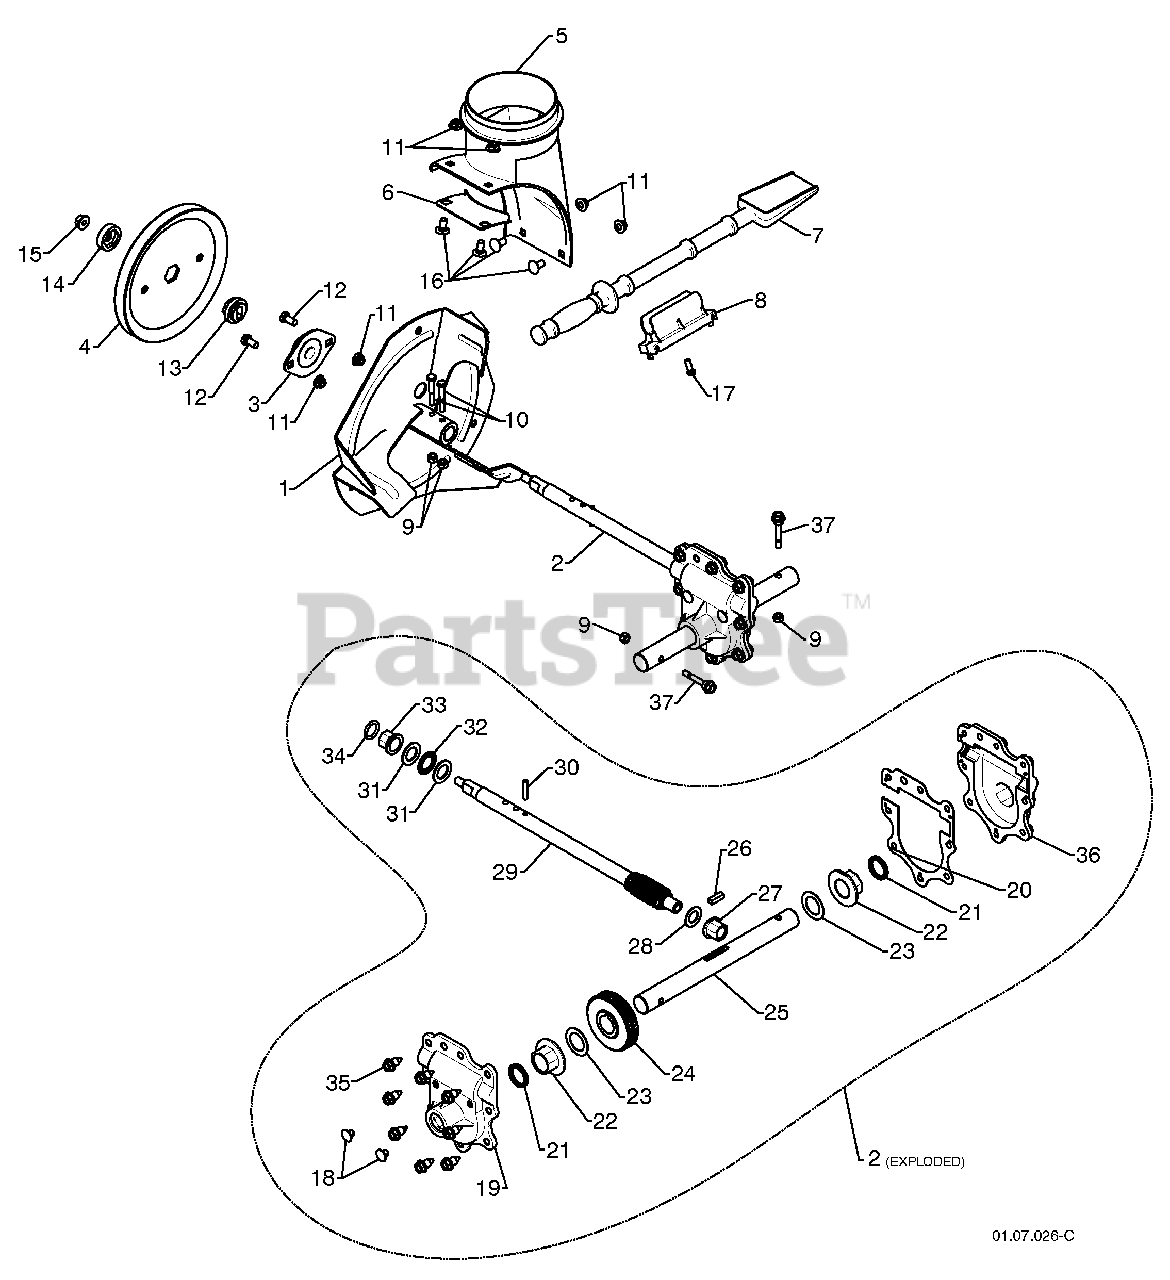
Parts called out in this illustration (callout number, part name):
1	IMPELLER
2	GEARBOX ASSEMBLY
3	BEARING
4	IMPELLER PULLEY
5	DISCHARGE BASE
6	CORNER BRACKET
7	CLEAN OUT TOOL
8	TOOL CLIP
9	NUT 1/4-20
10	SCREW 1/4-20 X .625
11	NUT 5/16-18
12	SCREW 5/16-18 X .625
13	IMPELLER HUB
14	IMPELLER SLEEVE
15	NUT 3/8-16
16	CARRIAGE BOLT
17	SCREW 13-16 X .625
19	GEARBOX COVER RH
20	GASKET
22	BEARING
23	THRUST WASHER 1.00
25	AUGER SHAFT
26	SQUARE KEY
28	THRUST WASHER
29	IMPELLER SHAFT
31	THRUST WASHER
32	THRUST BEARING
34	O-RING
35	SCREW 5/16-18 X .750
36	GEARBOX COVER LH
37	SHEAR BOLT
